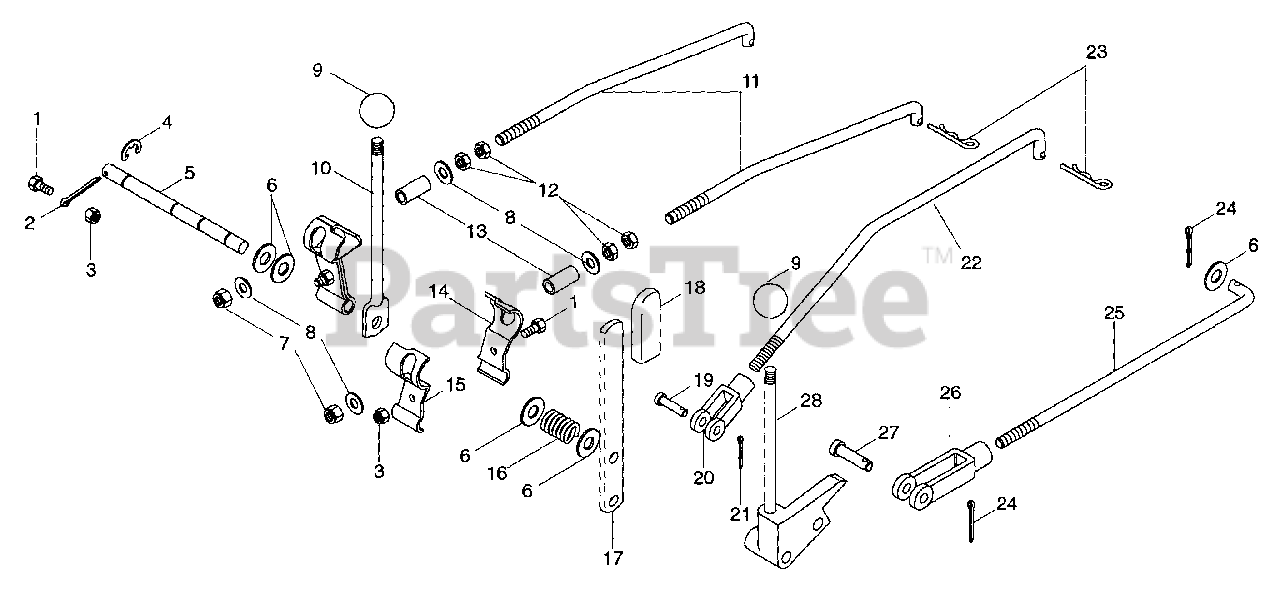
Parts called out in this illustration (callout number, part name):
1	Bolt-Hex .31-18 x .75 Grade 5
2	Pin-Cotter .250 x 2.00
3	Nut-Locking-Nylon .312-18 Grade 2
4	Ring-Retaining-External .500 x .042
5	Cross Shaft
6	Washer-Flat-Steel .531 x 1.062 x .095
7	Nut-Locking-Nylon .375-16 Grade 2
8	Washer-Flat-Steel .438 x 1.0 x .083
9	Knob-Control .438-20 x .50
10	Lever, Shift
11	Rod, Shift
12	Nut-Jam .375-16
13	Bushing-Sleeve .396 x .490 x 1.63
14	Arm, Shifter Right
15	Arm, Shifter Left
16	Spring-Compression .085 x .50 x 2.75
17	Lever, High-Low Shift
18	Grip, Handle
19	Pin, Clevis .375 x .948
20	Clevis .38-24 Adjustable
21	Pin-Cotter .09 x .75
22	Rod, 2-Speed
23	Pin-Hair Internal .08 x .18 x 1.18
24	Pin-Cotter .12 x 1.0
25	Rod, PTO
26	Yoke .50-20, Adjustable
27	Pin, Clevis .500 x 1.213
28	Assembly, PTO Control
